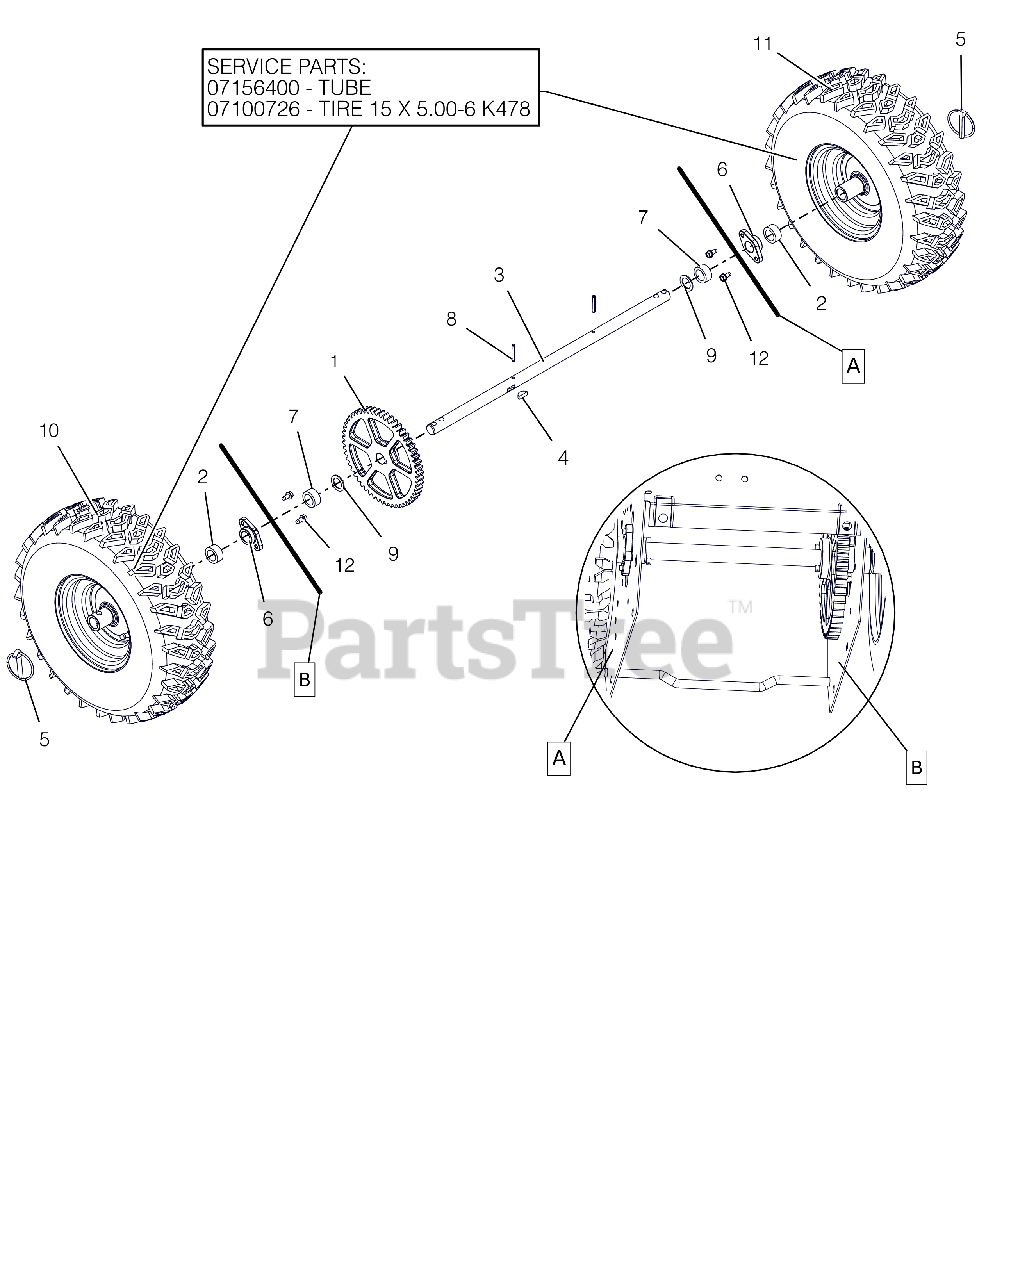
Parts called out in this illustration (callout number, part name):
1	SPUR GEAR, 54T .75ID X 6.75PD
2	BSHG-SLV .766 X 1.125 X .500
3	AXLE, COMPACT
4	KEY-WDRF .25X.750X.313 SAE91
5	PIN-LOK .31X1.75
6	BSHG .75X1.125X.65
7	BSHG-SLV .766 X 1.125 X .500
8	PIN-ROLL .188X1.25
9	WSHR-FL-STL.754X1.125X.062YWZC
10	TIRE/WHEEL,RH 15X5.00-6 PIN T2
11	TIRE/WHEEL,LH 15X5.00-6 PIN T2
12	SCR-TAP .25-20X.50 HWH TR YWZ
13	TUBE 15 X 5.00-6
13	TIRE, 15X5.00-6 K478
